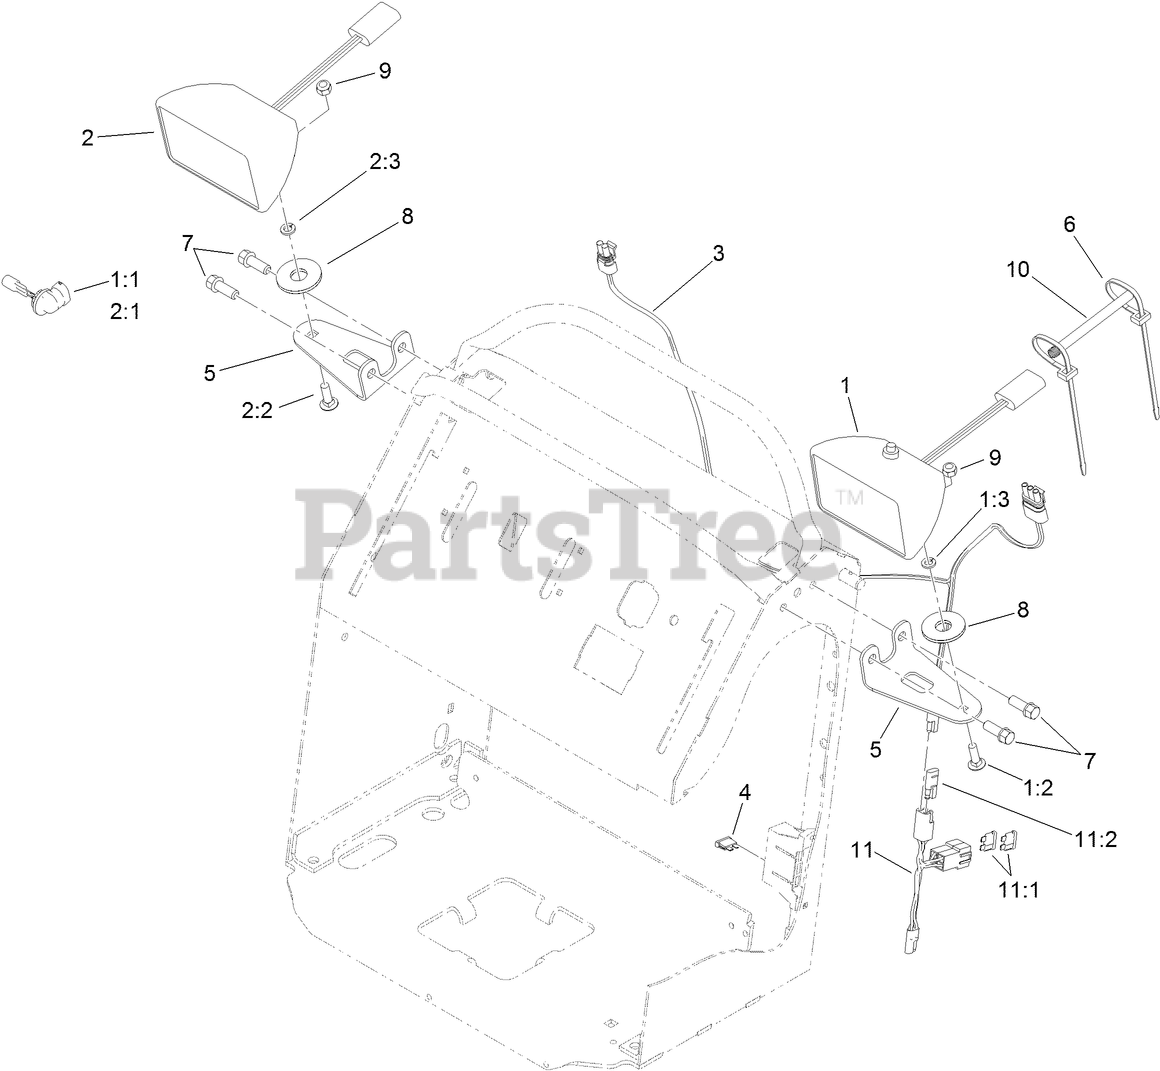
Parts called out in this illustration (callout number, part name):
1	LAMP W/SWITCH
1:1	LAMP-12 VOLT
1:2	SCREW-CARR
1:3	WASHER-LOCK
2	LAMP ASM
2:1	LAMP-12 VOLT
2:2	SCREW-CARR
2:3	WASHER-LOCK
3	HARNESS-WIRE
4	FUSE-BLADE, 15 AMP
5	BRACKET-MOUNT, LIGHT
6	TIE-CABLE
7	SCREW-HWH
8	WASHER-FRICTION, COMPOSITE
9	NUT-LOCK, NI
10	TUBE-CONVOLUTED
11	HARNESS-WIRE, FAN/LIGHT
11:1	FUSE-BLADE, 10 AMP
11:2	CAP-PLUG
